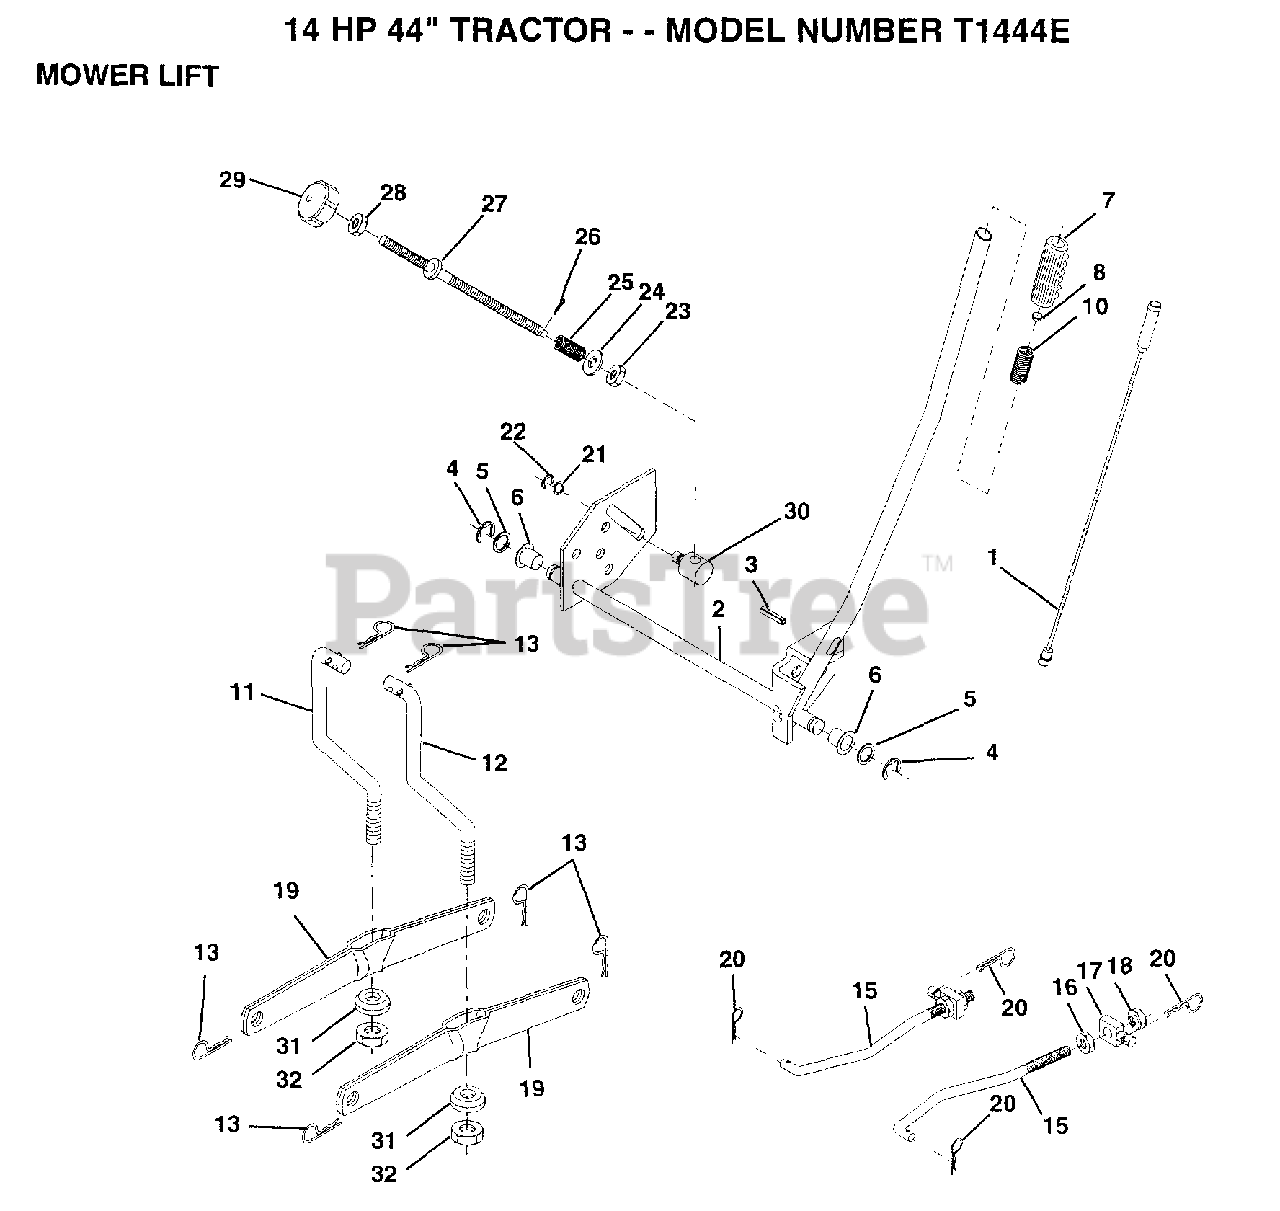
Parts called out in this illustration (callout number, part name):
1	WIRE.ASM.INNER
2	SHAFT.ASM.LIFT.RH
3	PIN GROOVE
4	E-RING
5	WASHER
6	NYLON BEARING
7	GRIP
15	LINK.FRONT
16	NUT
17	TRUNION
18	NUT.LK.W/WSH.1/2.
19	ARM SUSP REAR
20	RETAINER.SPRING
21	WASHER
22	KLIP RING
23	NUT T
24	WASHER
25	SPRING T
27	ROD LIFT LT
28	NUT
29	KNOB INF 3/8-16
30	TRUNION LT
31	BEARING PVT LH
32	NUT.LOCK.3/8-24
